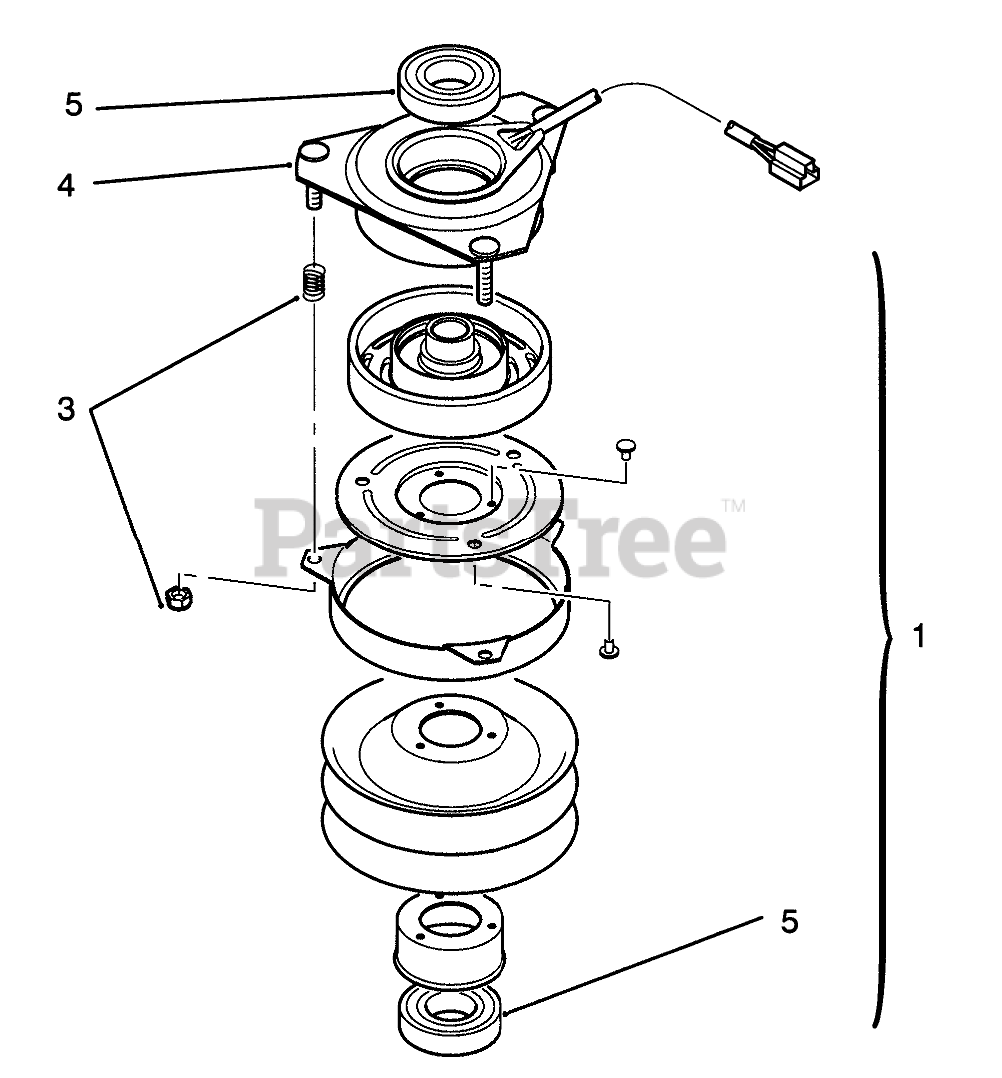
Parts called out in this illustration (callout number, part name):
1	Rotor & Armature Assembly (Incl. Ref. #5)
3	ACCESSORY PKG SRVC PART
4	Field-Assembly (Incl. Ref. #5)
5	BEARING-ELEC CLUTCH
